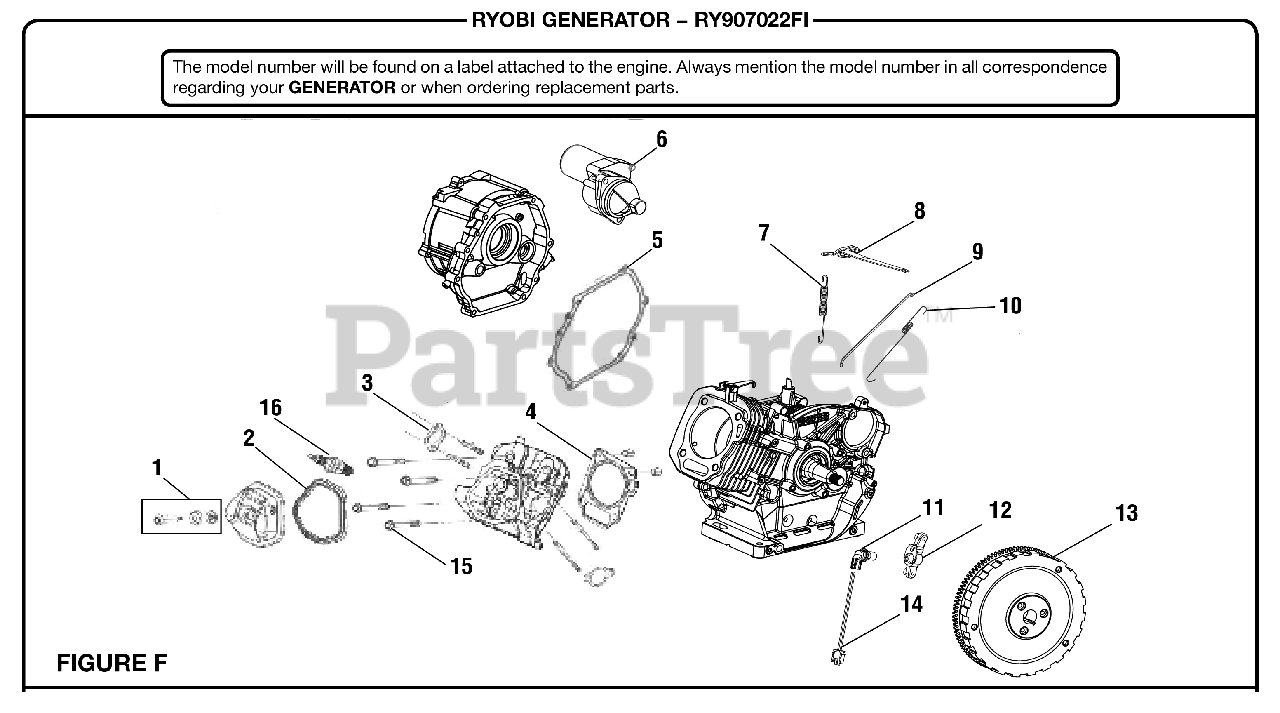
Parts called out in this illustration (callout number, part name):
2	Cylinder Head Cover Gasket
4	Cylinder Head Gasket
5	Crankcase Gasket
7	Governor Spring
8	Governor Support Assembly
10	Throttle Valve Return Spring
11	VR Sensor
12	VR Sensor Assembly Mount
13	FLYWHEEL SUBASSEMBLY
14	VR Sensor Wire Harness Pigtail
15	Cylinder Head Bolt
